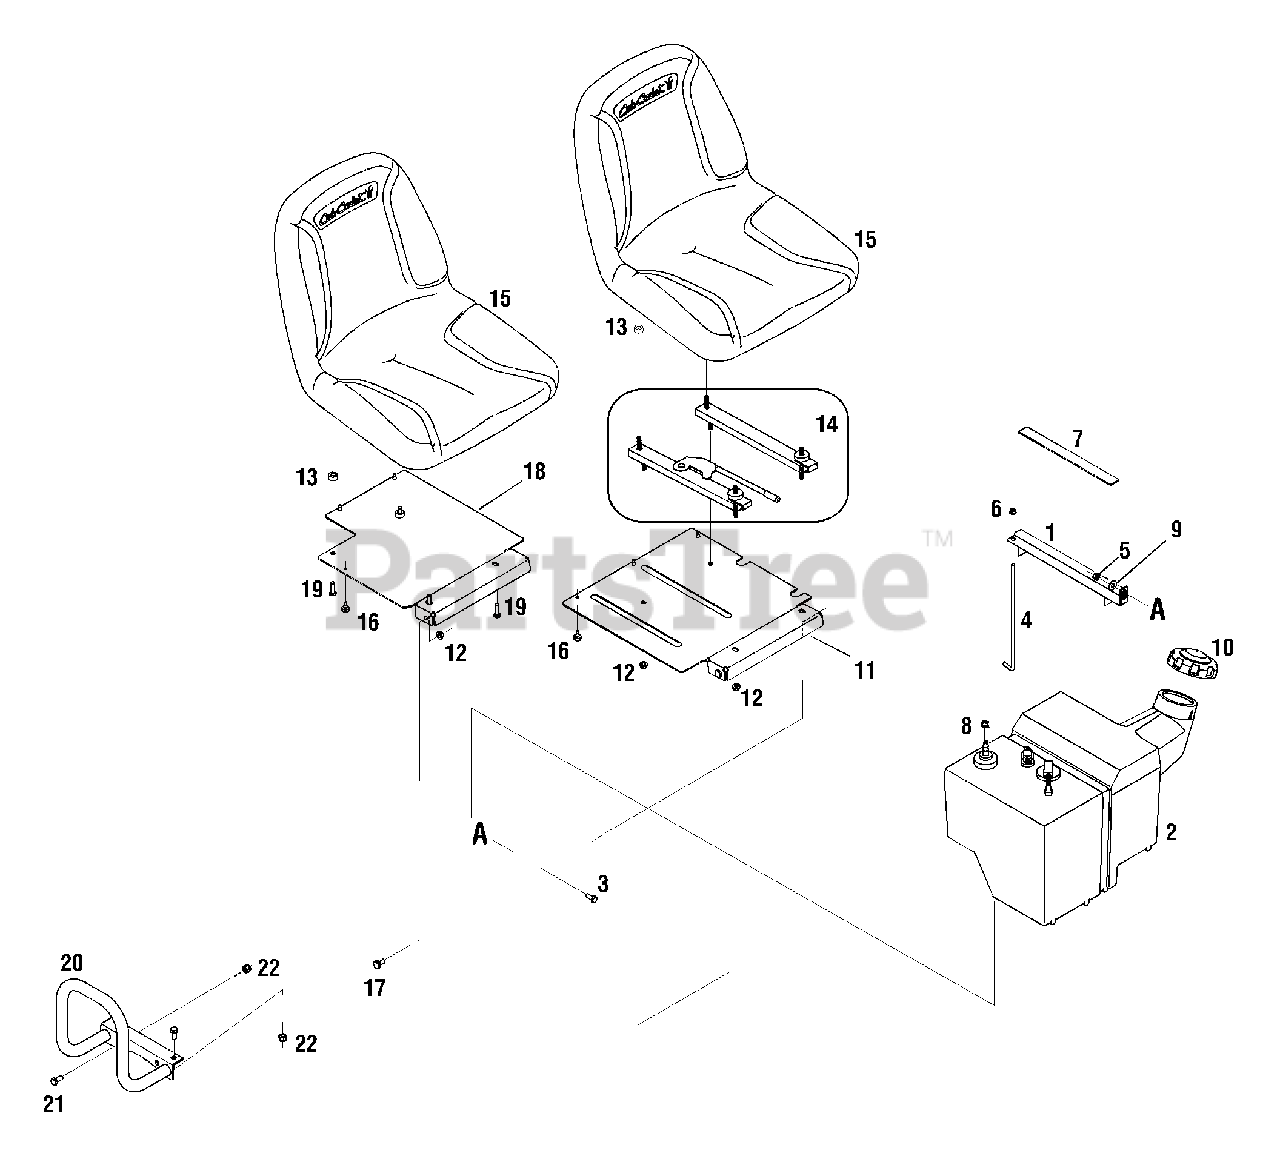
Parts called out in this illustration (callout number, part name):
1	Bracket Assembly, Fuel Tank
2	Tank Assembly, Fuel
3	Hex Screw, 5/16-18 x .75
4	Hold-down Rod, Fuel Tank
5	Sems Nut, 5/16-18
6	Nut, Flange Lock, 1/4-20
7	Gasket, Fuel Tank (11")
8	Clamp, Hose
9	Washer, .349 x .879 x .063
10	Cap, Fuel
11	Plate, Seat, LH
12	Nut, Flange Lock, 5/16-18, Gr5
13	Spacer, Seat
14	Track Assembly, Seat
15	Seat
16	Bumper
17	Shoulder Screw, .435 x .178-5/16
18	Plate, Seat, RH
19	Hex Screw, 5/16-18 x 1.0
22	Nut, Hex Lock Nylon, 3/8-16
